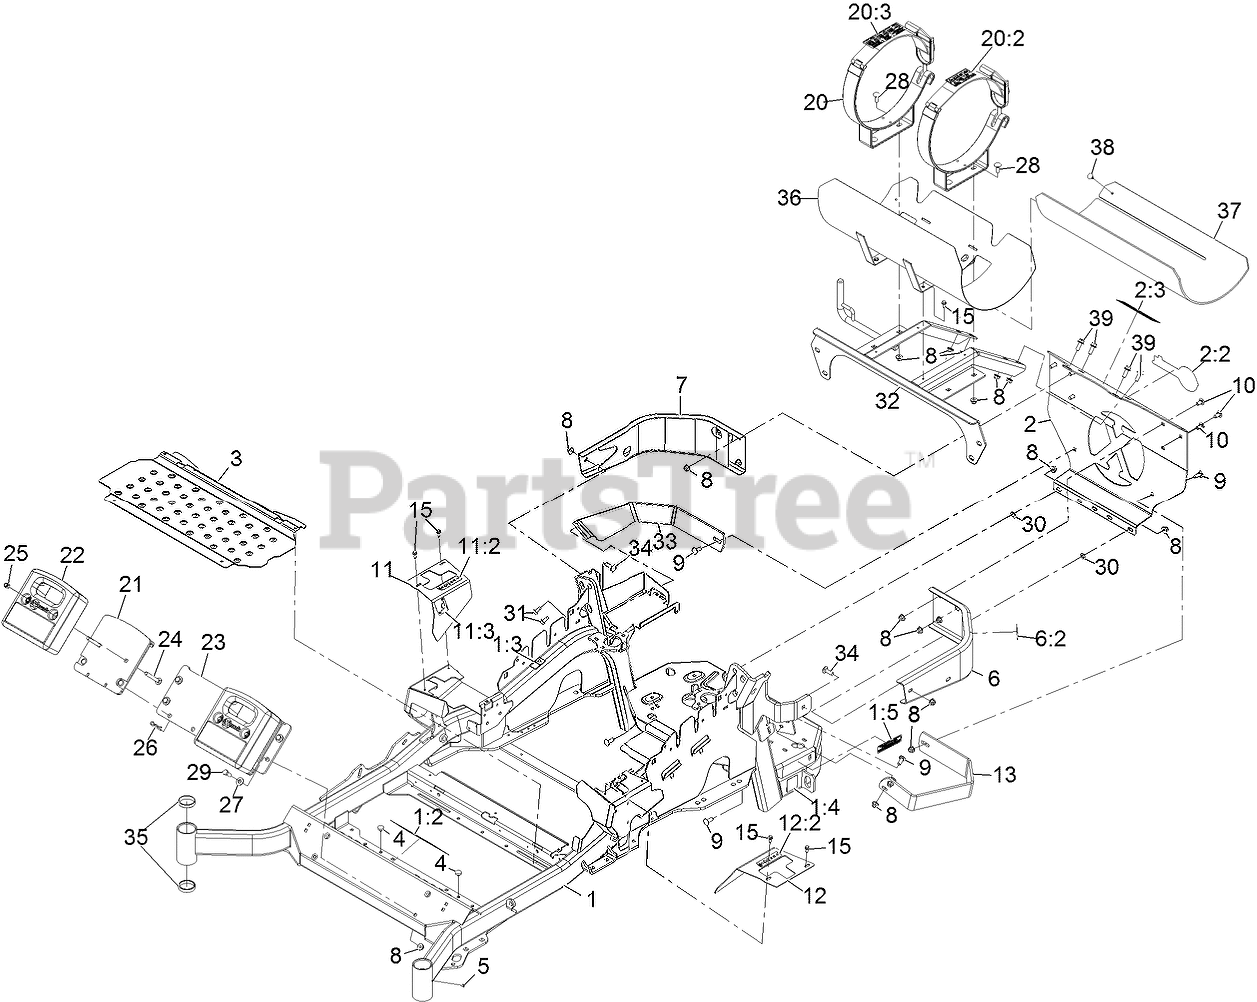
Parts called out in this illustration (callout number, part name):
1	MAINFRAME ASM
1:2	DECAL-DANGER
1:3	DECAL-WARNING
1:4	DECAL-HAZARD, PINCHED FINGER
1:5	DECAL-ARRESTOR, SPARK
2	REAR GUARD-LP W/DECALS
2:2	DECAL, EXMARK LOGO
2:3	Decal-LPG Fuel Tank Replacement
6	LH BUMPER ASM
6:2	DECAL-WARNING
7	BUMPER-RH
8	NUT-HF, NI
9	SCREW-CARR
10	SCREW-CARR
11	RH MOTION CONTROL COVER ASM
11:2	DECAL-CONTROL, MOTION
11:3	DECAL-PARK BRAKE, CE
12	LH MOTION CONTROL COVER ASM
12:2	DECAL-CONTROL, MOTION
13	GUARD-MUFFLER
15	SCREW-HWH
20	TANK BRACKET ASM (SET)
20:2	Decal-LPG Warning
20:3	Decal-LPG Tank Spec
21	WLD,WEIGHT MOUNT
22	WEIGHT,CAST 36LB
23	PLATE,WEIGHT ASM MOUNT
24	SCREW-CARR
25	NUT-LOCK, NI
26	PIN-HAIR
27	WASHER-BELLEVILLE
28	BOLT-CARR
29	SCREW-HH
30	NUT-PUSH
31	Screw-HWH 5/16-18 X 3/4 Tf
32	SUPPORT-TANK
33	STRAP-GUARD
34	BOLT-CARR
35	CUP-BEARING
36	Wld,LP Tank Heat Shield
37	THERMAL BARRIER-43# LP TANK
38	PLUG-PLASTIC
39	SCREW-HHF 3/8-16 X 1
